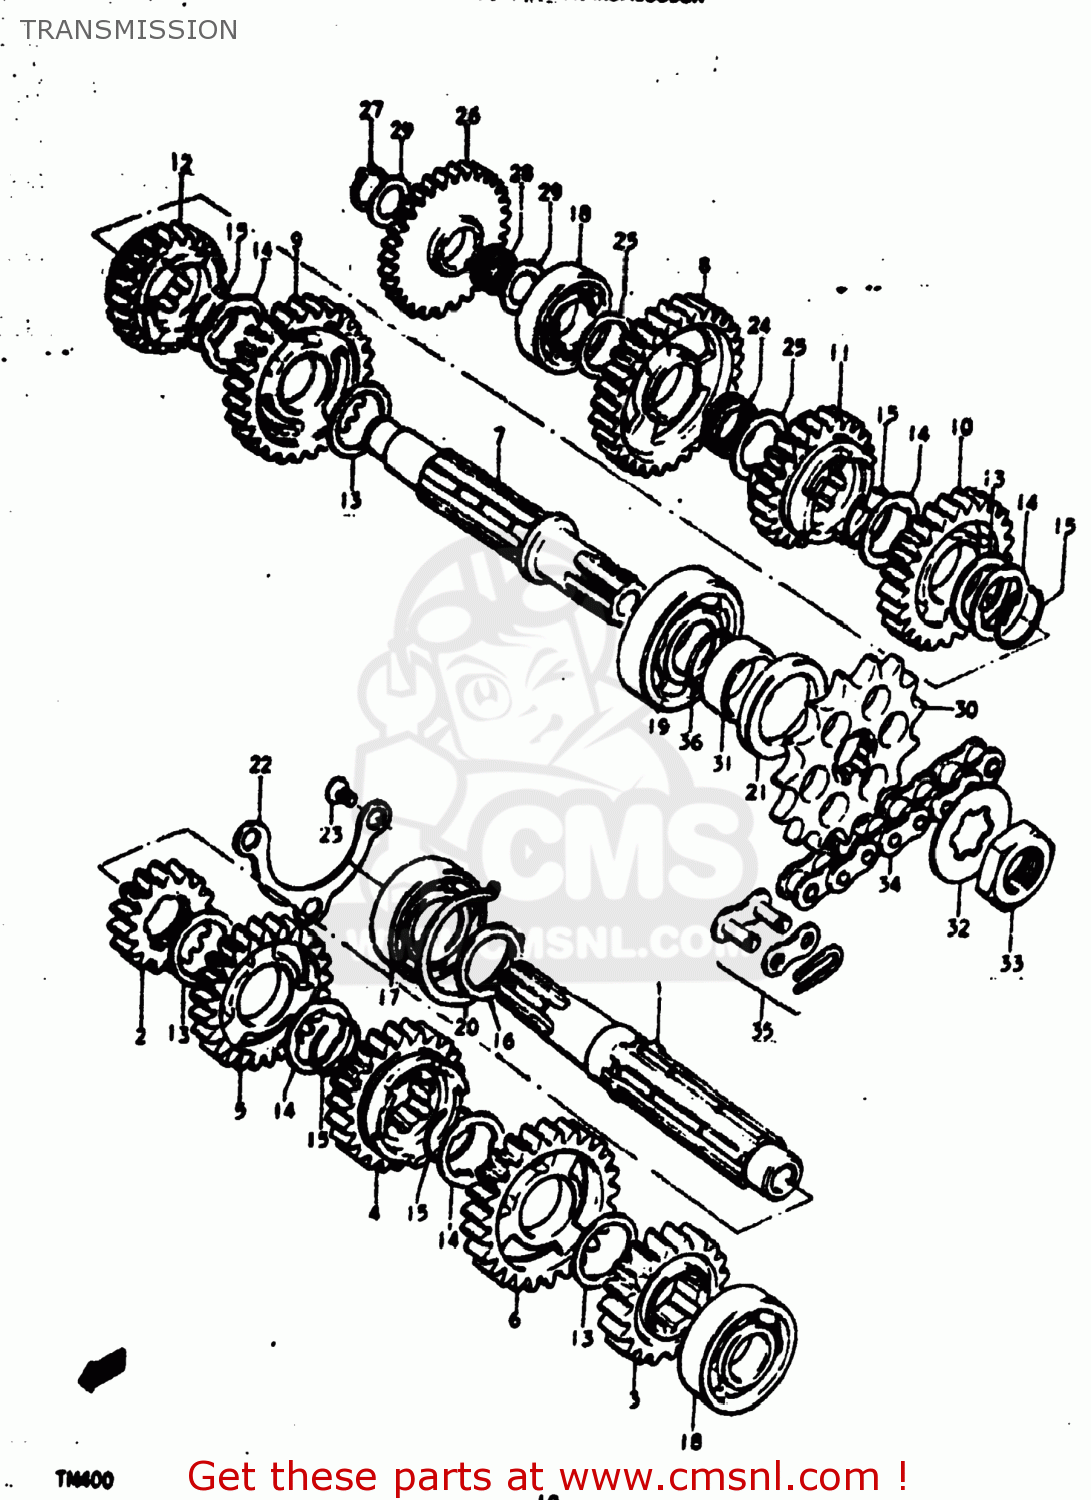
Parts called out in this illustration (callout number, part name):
1	SHAFT,COUNTER
3	GEAR,SECOND DRIVE
4	GEAR,THIRD DRIVE
5	GEAR,FOURTH DRIVE
6	GEAR,FIFTH DRIVE
7	SHAFT,DRIVE
8	GEAR,FIRST DRIVEN
9	GEAR,SECOND DRIVEN
10	GEAR,THIRD DRIVEN
11	GEAR,FOURTH DRIVEN
12	GEAR,FIFTH DRIVEN
13	WASHER
14	WASHER
15	RING,SNAP
16	WASHER
17	BEARING
18	Bearing
19	BEARING
20	CIRCLIP
21	SEAL,OIL(32X42X6)
22	RETAINER,BEARING
23	SCREW
24	BEARING
25	WASHER (20X30X1)
26	GEAR,KICK STARTER IDLE
27	CIRCLIP
28	BEARING(17X21X9.8)
29	WASHER
30	SPROCKET,ENGINE
31	SPACER (22X32X13.4)
32	WASHER,LOCK
33	NUT
34	CHAIN ASSEMBLY,DRIVE
35	JOINT ASSEMBLY,CHAIN
36	O RING(D:1.7,ID:22)
